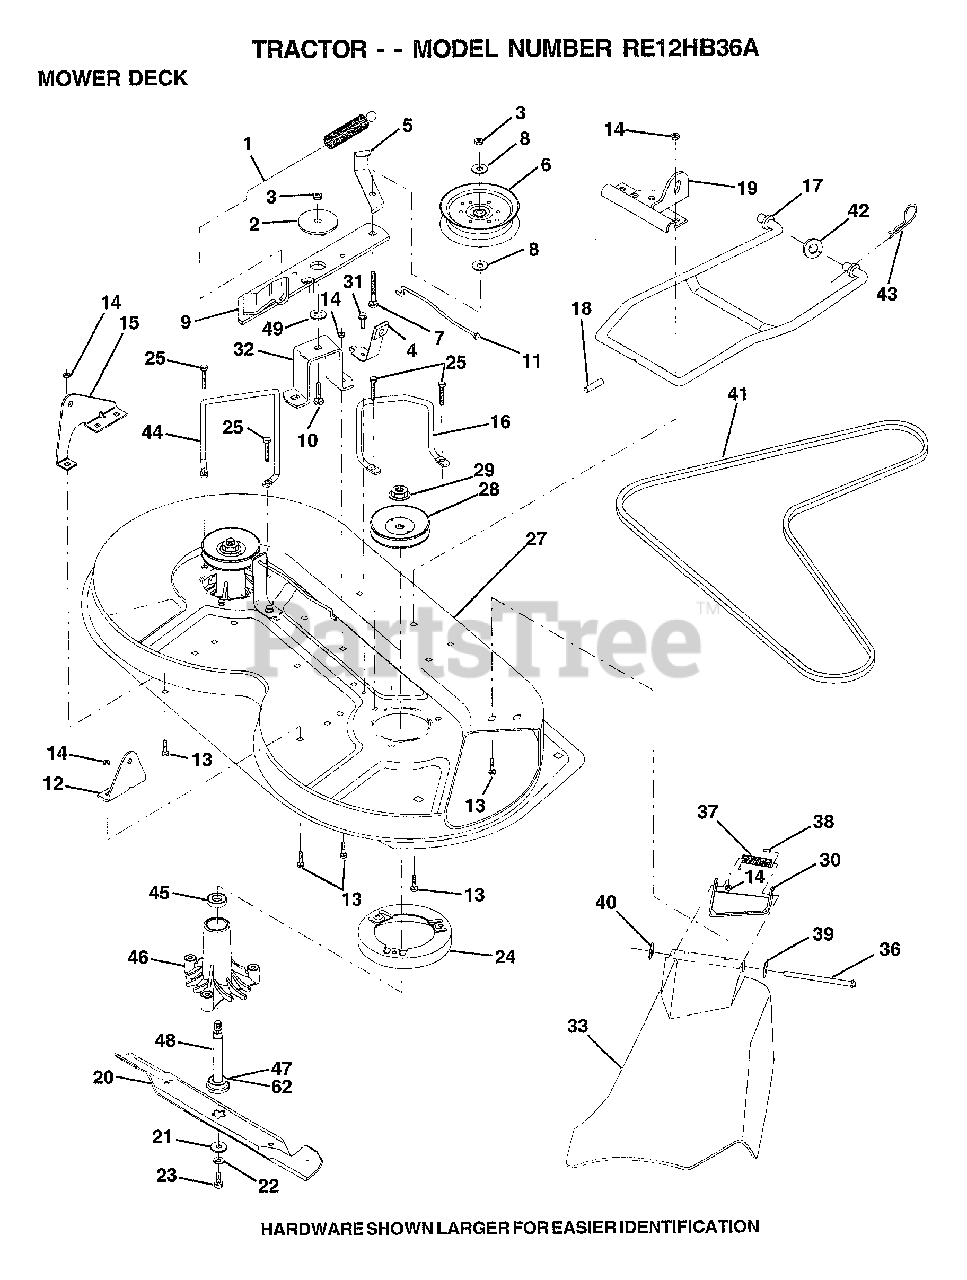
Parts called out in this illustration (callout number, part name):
1	SPRING CLUTCH MWR
2	SPACER.RETAINER.MOWER
4	BRAKE ASM
5	IDLER BELT GUIDE
6	PULLEY IDLER
7	BOLT
8	WASHER
10	BOLT.3/8-14X1.25
11	BRAKE ROD
12	"BRKT,LIFT REAR"
13	BOLT
15	"BRKT,LIFT REAR LH"
16	"KEEPER-BELT,RH"
17	MOWER LINK STAB
18	"PIN,GROOVE"
19	"BRKT,LINK STABILI"
20	"BLADE.36"" HIPERF"
21	WASHER.HARD.BLADE
23	BLADE BOLT
24	STRIPPER RND MWR
25	"SCREW-THD ROLL,WA"
27	"HOUSING-MOWER,36"""
28	PULLEY.MAND.36/46
31	SCREW LT
32	"SUPT,IDLER ARM"
33	SHIELD, DEFLECTOR
36	HINGE ROD
37	SPRING TORSION
38	CAP-SLEEVE LT
39	WASHER
40	NUT PUSH M
41	V-BELT.PRIM.78.5.
43	RETAINER SPRING
44	KEEPER BELT LH
45	BEARING
46	HSG ASM MANDREL
47	BEARING.BALL
49	HARDENED WASHER
62	WASHER.FELT.
